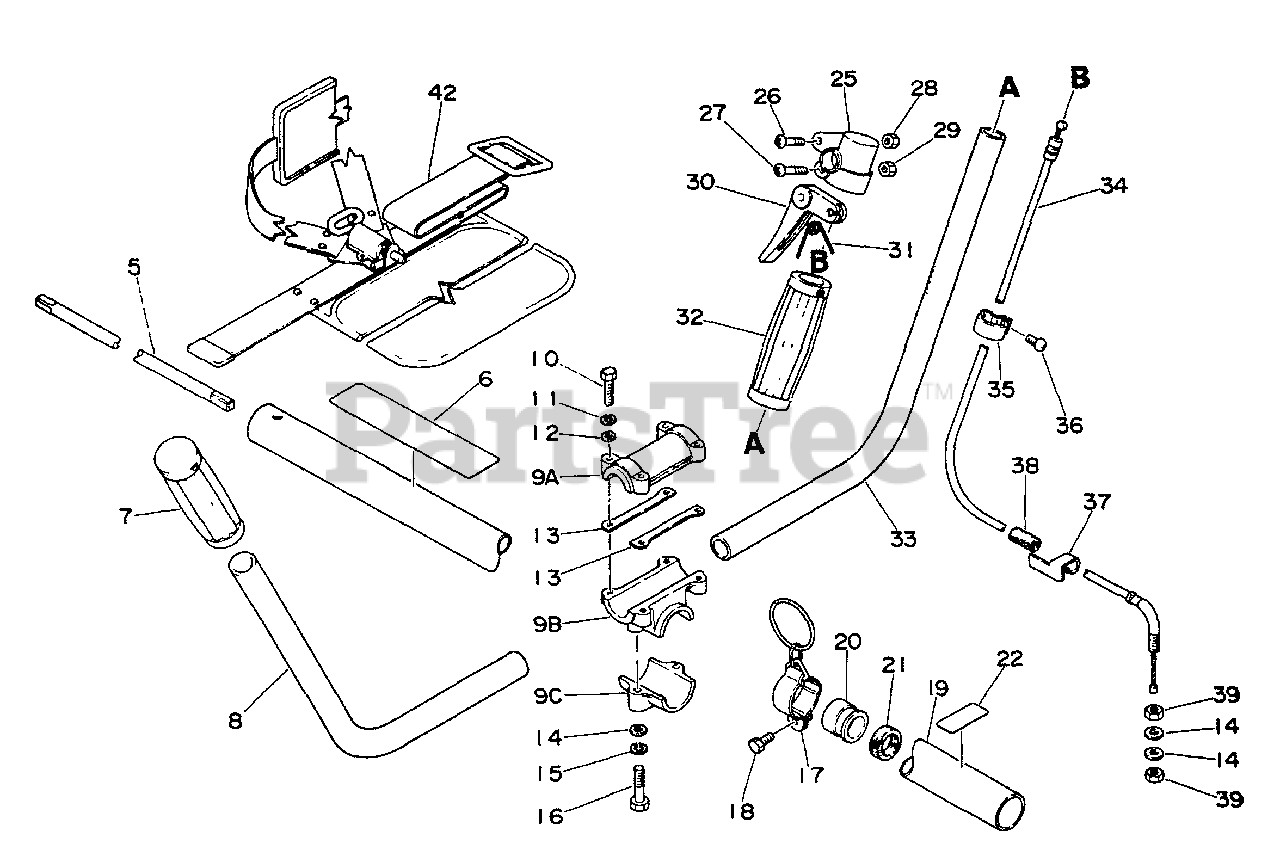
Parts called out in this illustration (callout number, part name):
5	DRIVESHAFT
6	LABEL - CAUTION
7	GRIP, HANDLE - LEFT
8	HANDLE, FRONT - LEFT
9	HANDLE BRACKET KIT
9A	HANDLE BRACKET KIT
9B	HANDLE BRACKET KIT
9C	HANDLE BRACKET KIT
10	BOLT - 5X25
11	LOCKWASHER - 6
12	WASHER - 5
14	WASHER - 6
15	LOCKWASHER - 6
16	BOLT - 6X30
17	HANGER KIT
18	BOLT - 5X12
19	MAIN PIPE ASSY
22	LABEL - ALIGNMENT
25	BRACKET, TRIGGER
26	SCREW - 5X30
27	SCREW - 5X25
28	LOCKNUT - 5
30	TRIGGER, THROTTLE
31	SPRING, TRIGGER
32	GRIP, HANDLE
34	CABLE, THROTTLE
36	SCREW - 5X10
38	TUBE
42	SHOULDER STRAP ASSY
